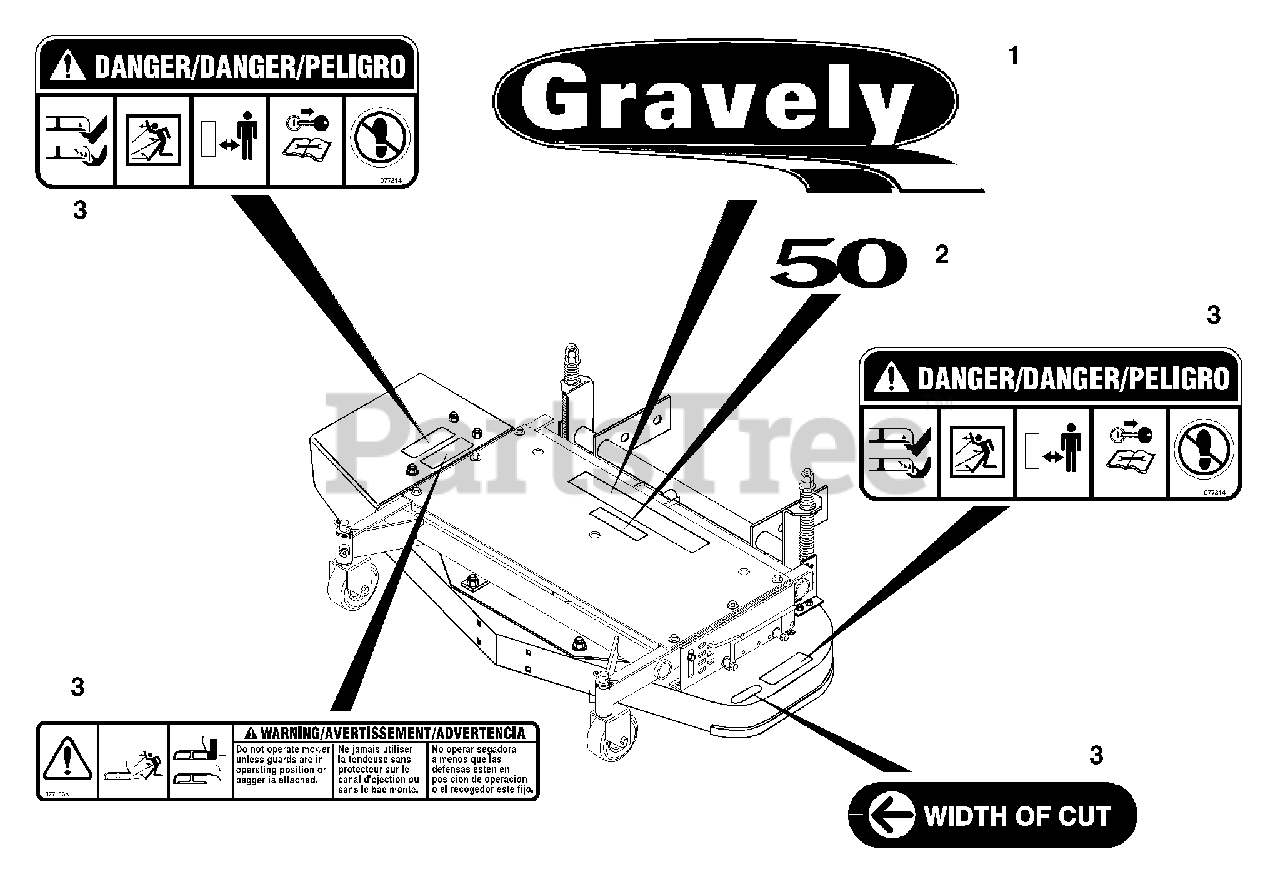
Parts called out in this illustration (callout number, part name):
1	Decal, Gravely Logo
2	Decal, Pro-50
3	Decal Set, Deck
